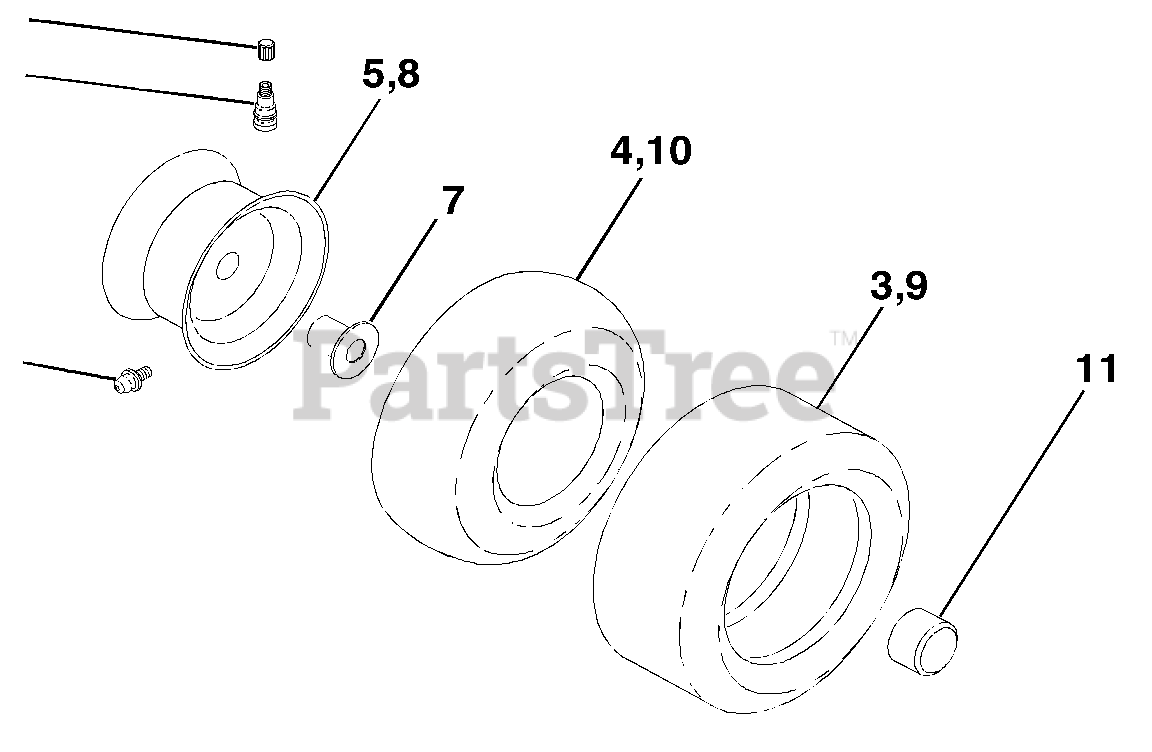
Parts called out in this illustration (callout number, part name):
1	Cap Valve Tire
2	Stem Valve
3	Tire F Ts 15 X 6 0 - 6 Service
4	Tube Front
5	Rim Asm 6" front White Service
6	Fitting Grease
7	Bearing Flange
8	Rim Asm 8" rear White Service
9	Tire R Ts 18x9.5-8 C Service
10	Tube Rear
11	Cap Axle Blk 1 50 X 1 00
